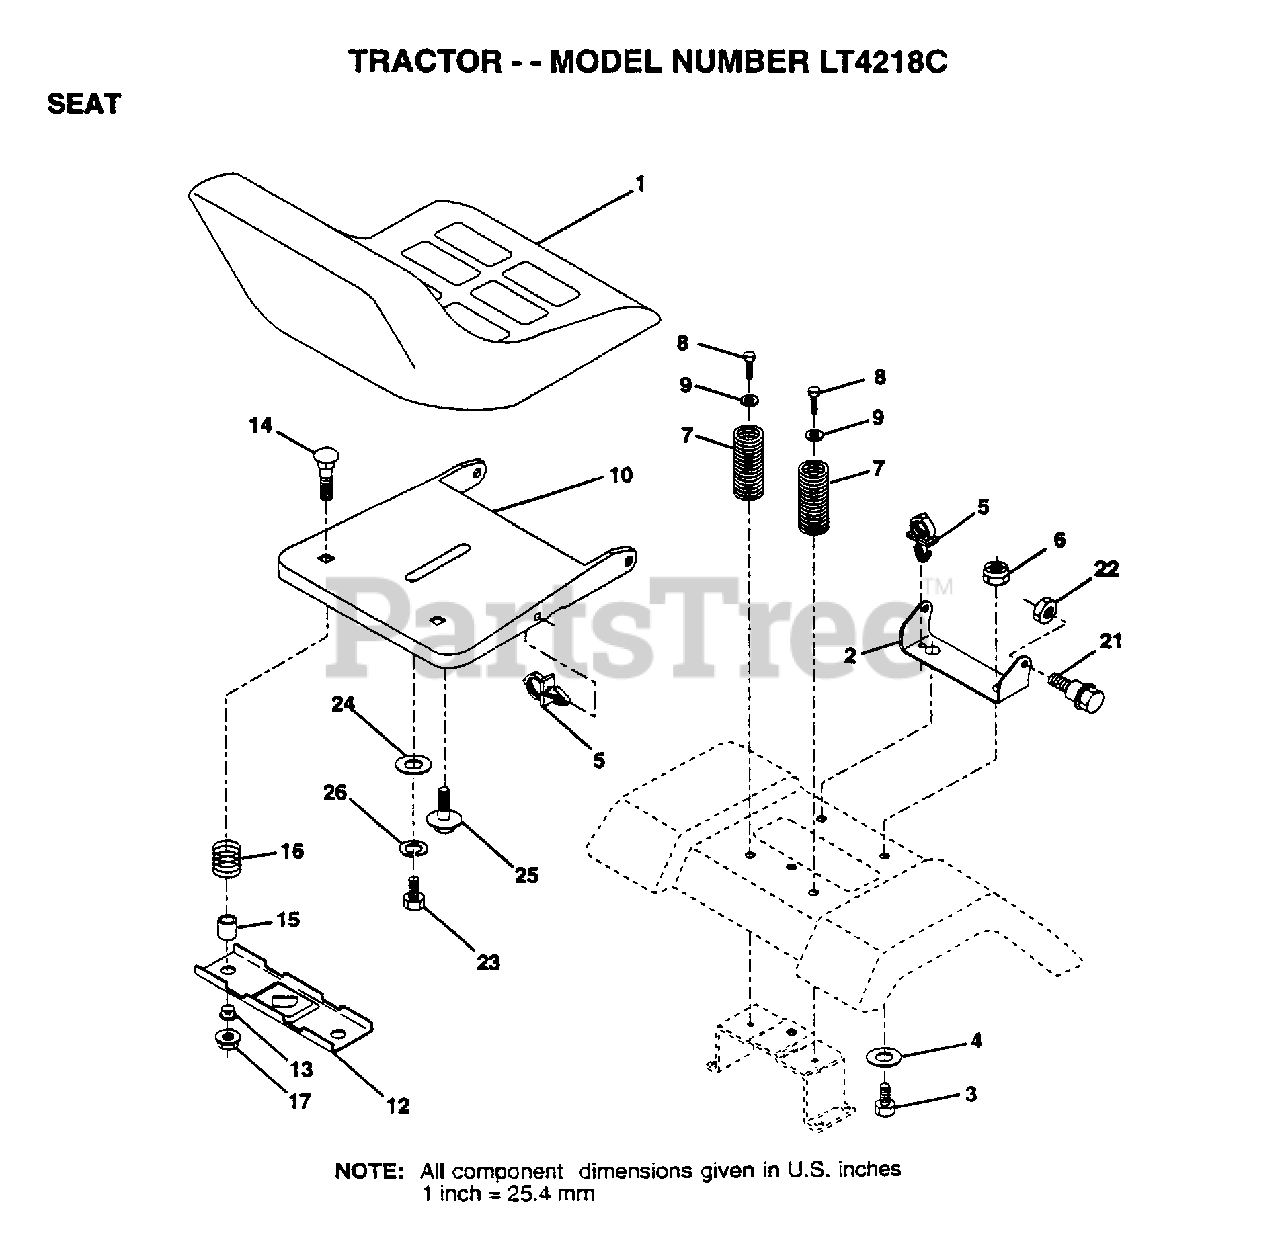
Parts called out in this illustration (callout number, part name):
2	BRACKET PVT SEAT
3	BOLT
4	WASHER PM
5	CLIP.PUSH-IN.HING
6	NUT
7	SPRING COMPRESSIO
8	SCREW GTV
9	WASHER
12	BRKT SWITCH
13	BUSHING
15	SPACER SPLIT
16	SPRING COMPRESSED
21	BOLT.SHLD.5/16-18
23	BOLT
24	WASHER
25	"BOLT,SHOULDER"
26	LOCKWASHER
